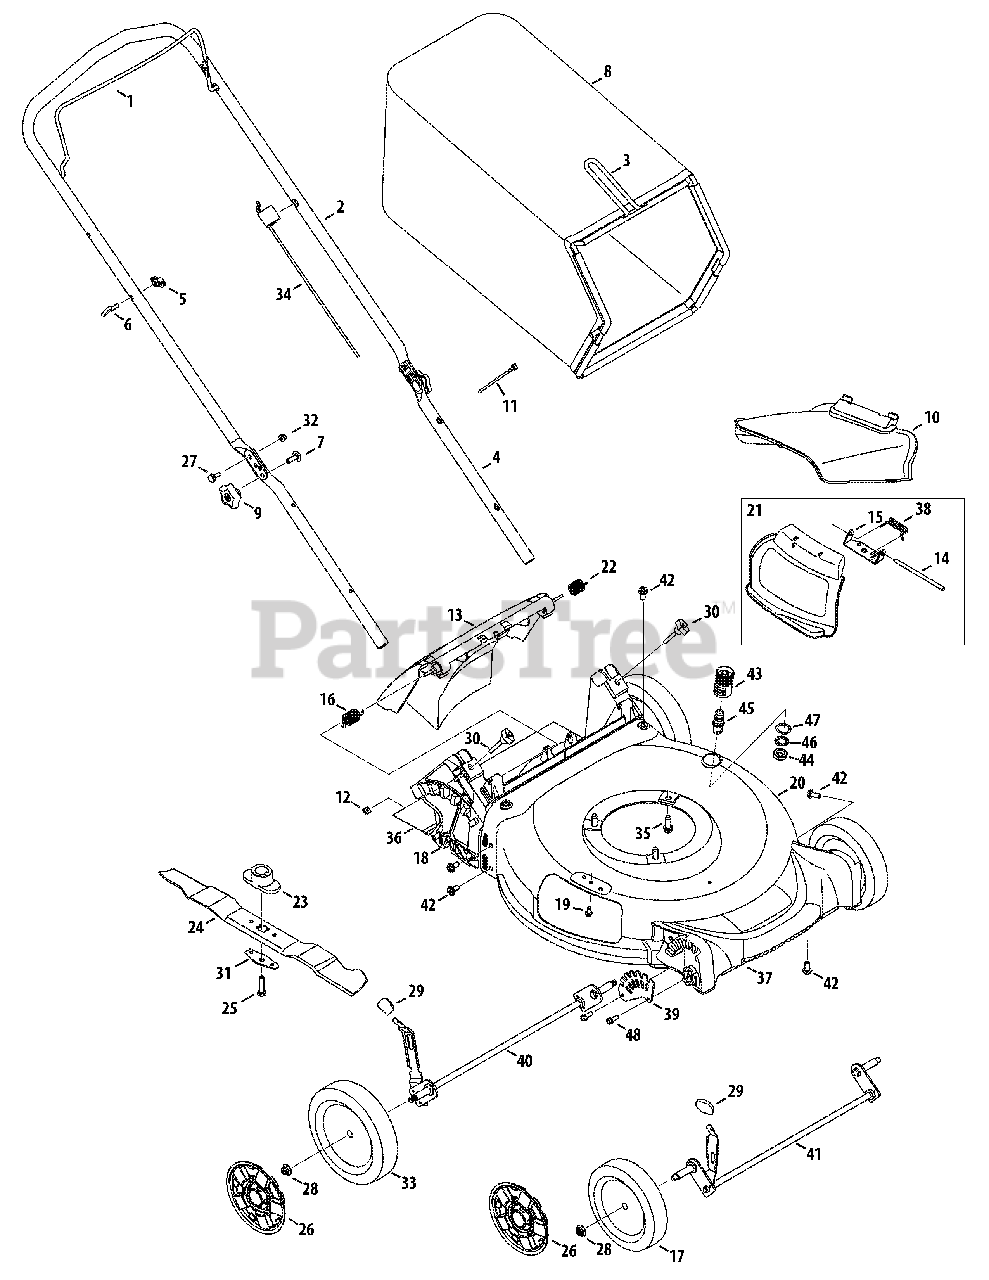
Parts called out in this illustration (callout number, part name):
1	Blade Control
2	Upper Handle
3	Grass Catcher Frame
4	Lower Handle
5	Wing Nut
6	Rope Guide
7	Carriage Screw, 5/16-18
8	Grass Bag
9	Hand Knob
10	Side Chute
11	Cable Tie
12	Nut, Sq., 1/4-20
13	Rear Discharge Door
14	Hinge Pin
15	Chute Deflector Bracket
16	Torsion Spring - RH
17	Wheel, 7 x 2
18	Rear Baffle
19	Screw, 1/4-20 x .500
20	Deck - 21"
21	Hinged Mulch Plug Assembly
22	Torsion Spring - LH
23	Blade Adapter
24	Mulching Blade
25	Screw , 3/8-24 x 1.50
26	Hub Cap - Front
26	Hub Cap - Rear
27	Sldr. Screw, .375 x .126 x 1/4-20
28	Flange Lock Nut, 3/8-16
29	Adjustment Lever Knob
30	Wing Nut
31	Blade Bell Support
32	Nut, Flange Lock, 1/4-20
33	Wheel, 8 x 2
34	Control Cable
35	TT Sems Screw, 3/8-16 x 1.0
36	Trail shield
37	Front Cover
38	Torsion Spring
39	Front Height Adjuster Plate
40	Rear Axle Assembly
41	Front Axle Assembly
42	Screw, 5/16-14 x .750
43	Water Nozzle
44	Nut, Hex, M16-1.5
45	Water Nozzle Adapter
46	Washer, Lock, 5/8
47	Washer, Flat, .865 x 1.145 x .030
48	Screw, 1/4-15 x .750
